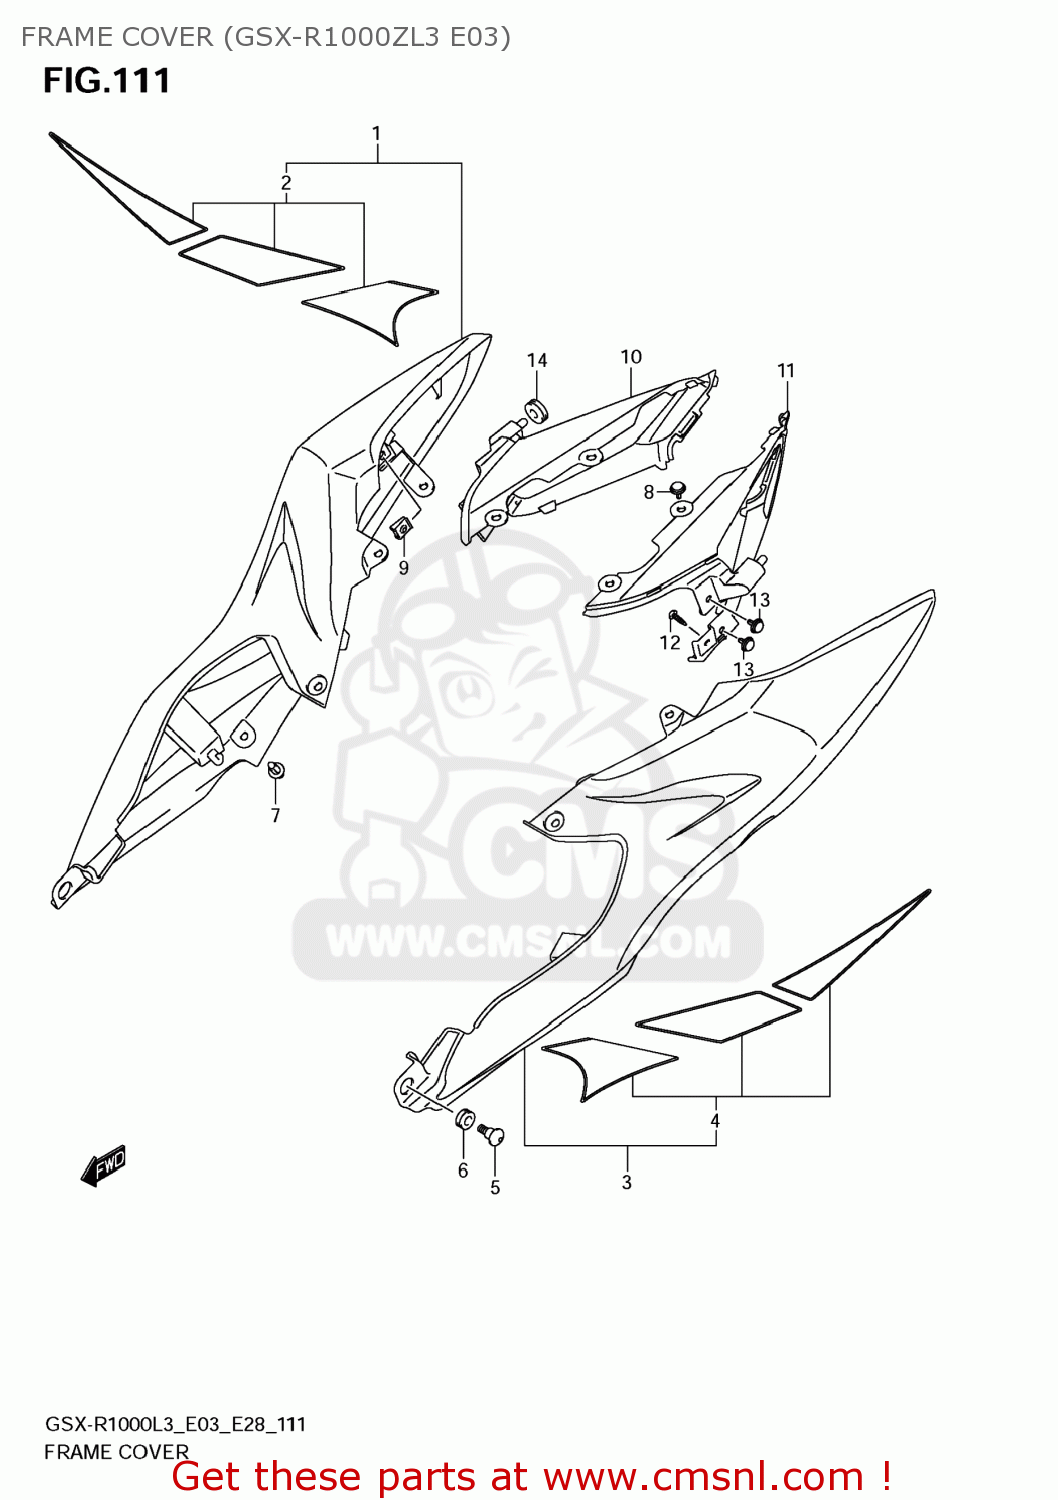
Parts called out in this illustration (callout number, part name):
1	COVER,FRAME,R(WHITE)
2	TAPE SET,FRAME COVER,R
3	COVER,FRAME,L(WHITE)
4	TAPE SET,FRAME COVER,L
5	SCREW,SIDE COVER LWR,R
6	CUSHION
7	CLIP(BLACK)
8	CLIP
9	NUT
10	COVER,FRAME RR,R
11	COVER,FRAME RR,L
12	SCREW
13	CLIP
14	CUSHION
